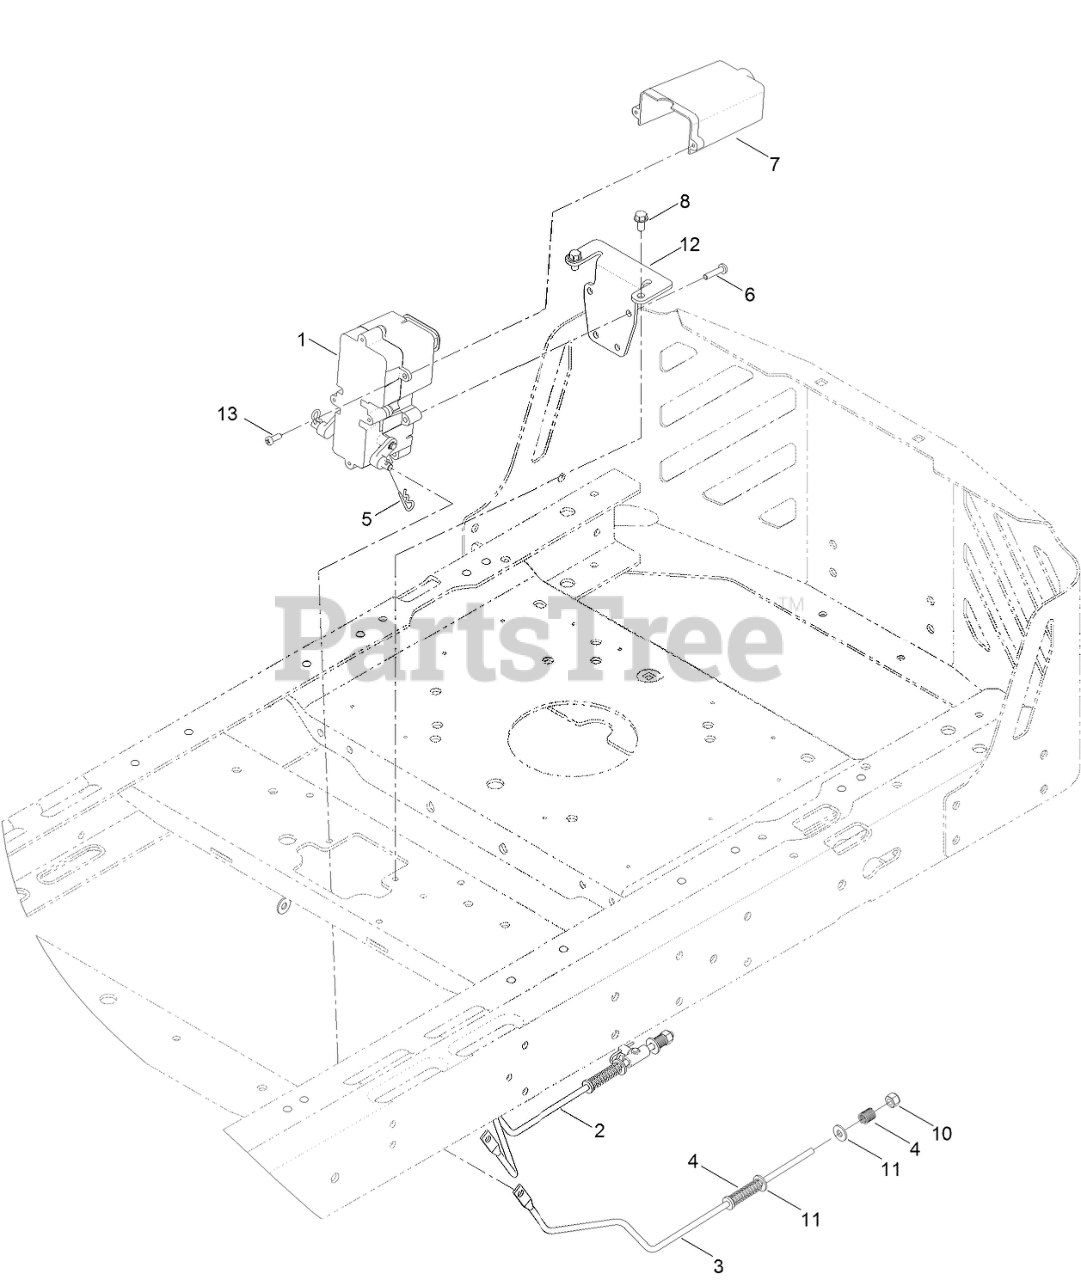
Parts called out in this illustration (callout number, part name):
1	BRAKE BOX ASM
2	ROD-BRAKE, RH
3	ROD-BRAKE, LH
4	SPRING-COMPRESSION
5	PIN-COTTER
6	SCREW-PPH
7	COVER-CONNECTOR
8	SCREW-HWH
10	NUT-LOCK, NI
11	WASHER
12	BRACKET-MOUNT, BRAKE
13	SCREW-PPH
